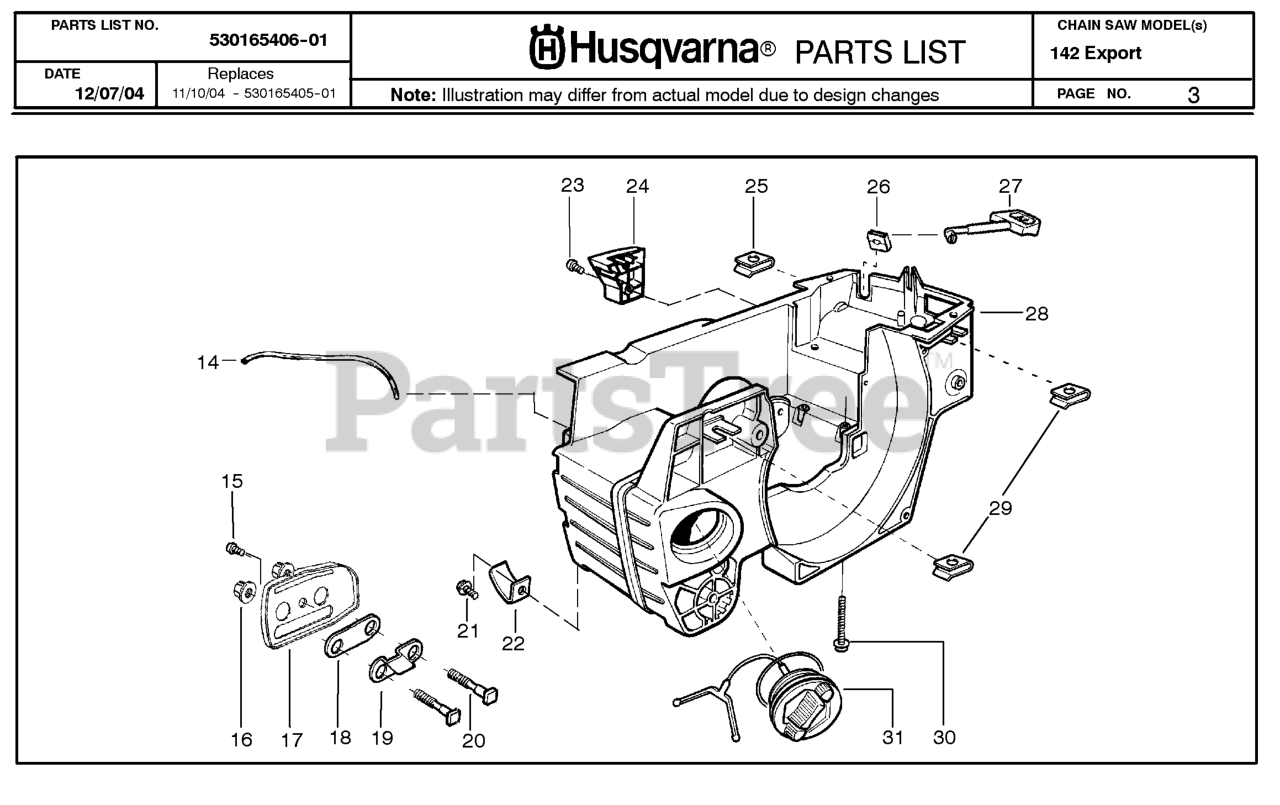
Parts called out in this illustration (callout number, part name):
8	ROD SHIFT FENDER ADJUST LT
9	CLUTCH.ELECTRIC.OGURA.EURO.
10	PIN COTTER
14	LOCKWASHER
14	TUBE
15	BOLT HEX 5/16-18 GR 5
16	NUT.71038.31-18.HEX.NYLOCK
18	OIL TANK GASKET
19	NUT
19	PLATE,BAR MOUNT
20	BOLT HEX 7/16-20X4-1/4"
20	BAR BOLT 36/41
21	KNOB.DUCKHEAD.1/2
22	ROD
22	CHAIN CATCHER 36/41
24	NUT
24	LIMITER COVER
25	SPRING BRAKE ROD
26	CHOKE GUIDE 36/41
27	COTTER PIN
27	CHOKE 36/41
28	ROD, PARKING BRAKE
28	KIT ASSY CHASSIS
29	PLUNGER CAP
30	BRKT, TRNSXLE MNT 20"
30	SCREW M5-0.8X35M TAP
34	SHAFT, FOOT PEDAL
35	BEARING.NYLON
37	DRIVE PIN
38	PULLEY.FLAT
42	WASHER
47	IDLER PULLEY
48	BELLCRANK, CLUTCH
49	RETAIN BELT
50	BOLT.3/8-16X1.50
52	LOCKNUT
53	LINK.CLUTCH.7.66.2005
55	SPRING, RETURN LT
56	SCREW.3/8-16
57	V-BELT 113"
62	COVER, PEDAL (1 2)
63	PULLEY.ENGINE.CVX.LT
65	LOCKWASHER
66	KEEPER BELT ENGINE
71	STRAP TORQUE LH HYDRO
73	STRAP TORQUE RH HYDRO
74	SPACER AXLE
77	SQUARE KEY
81	ASM.CROSS.SHAFT.REAR.CRD.0510
82	SHIFT SPRING
83	WASHER
84	LINK.PNT.TRANSAXLE.0510.CRD
95	LINK
96	RETAINER M
120	NUT LOCK FLG 3/8-16 UNC
150	BUSHING.BELLCRANK.GRD.DR
151	WASHER 12/32X2X10GA
156	WASHER.SRRTD.5/16
158	BRACKET
159	RB HUB.SHIFT
161	BOLT
162	NUT.CROWNLOCK.1/4
165	RP BRACKET
166	CAPSCREW.HXHD.FLG.5/16-18X.625
167	BRACKET.SUPT.SHIFT.CRD
168	BOLT.SHOULDER.5/16-18X
169	PLATE.FASTENING.CROSS.SHAFT
172	LINK
181	BRACKET
182	BELT GUIDE
183	PULLEY.V-IDLER.GRND.DR
185	LINK
186	HUB.TAPERED.ROUND.CRD
187	BOLT.5/16-18X1.25
197	NYLINER SNAP 5/8" ID
199	BOLT SHOULDER 5/16-18 UNC
207	WASHER NYL
214	LEVER
215	ROD
243	BRACKET, ANTI-ROTATION
252	WASHER
254	SCREW 3/8-16X1
255	SHAFT
258	CLIP RETAINER
259	BRACKET
261	FLAT IDLER PULLEY
263	SCREW, 3/8-16X3/4
266	PROTECTOR
292	SPACER
295	PULLEY IDLER COMPOSITE
297	SCREW LT.3/8-46X5/8
